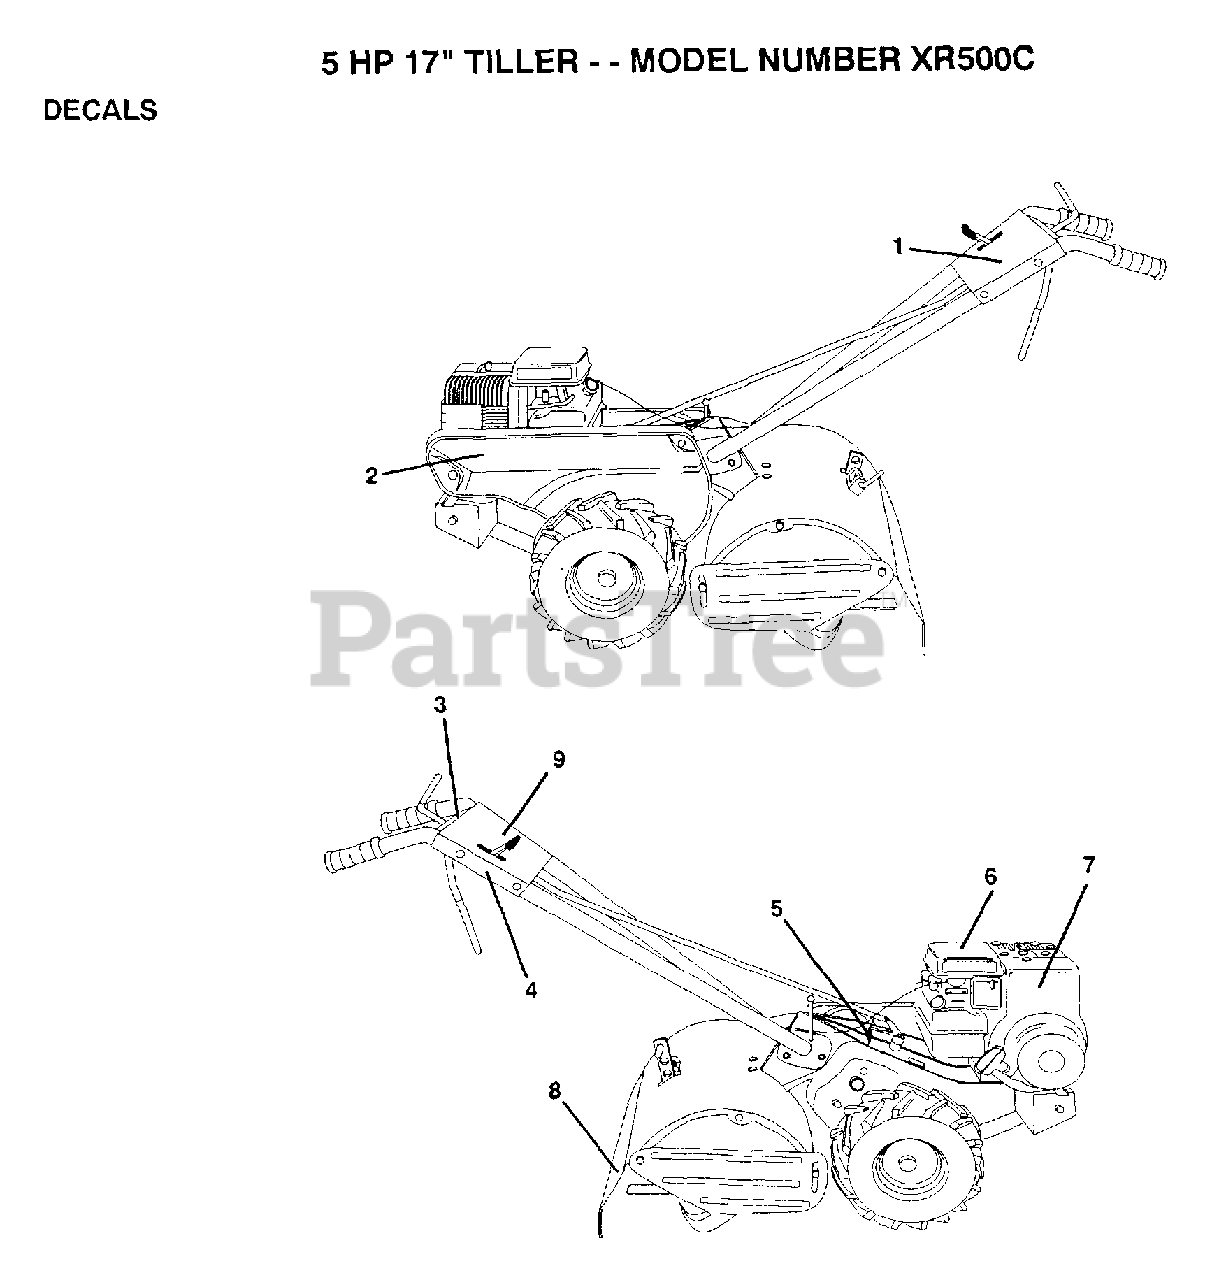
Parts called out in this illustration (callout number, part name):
1	"DECAL,BRKT HDLE T"
4	DECAL TI
6	DECAL TI
9	DECAL, THROTTLE CONTROL
